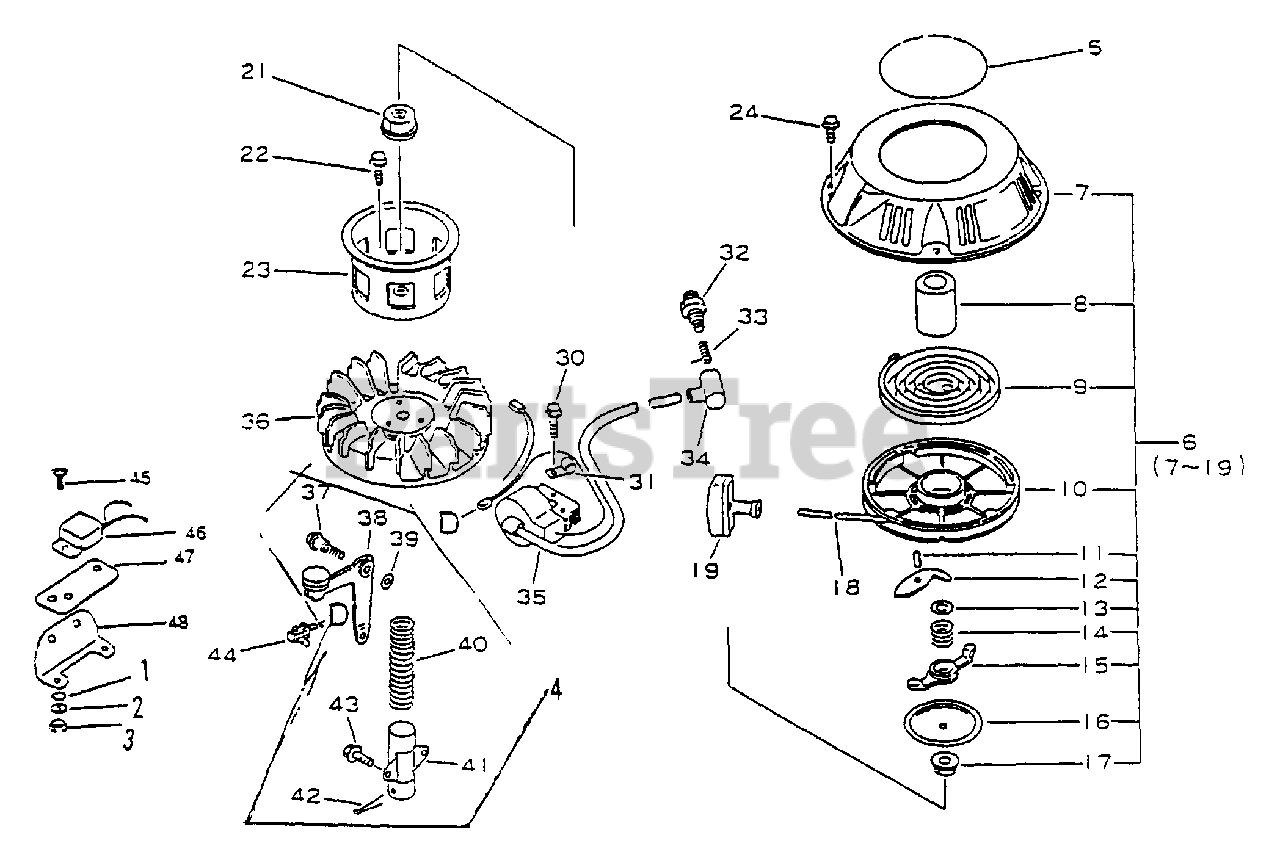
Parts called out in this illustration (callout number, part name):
1	WASHER 4 MM
2	WASHER, SPRING 4 MM
3	NUT M4
4	CHAIN BRAKE ASSY
5	LABEL - ECHO
6	STARTER ASSY
7	CASE, STARTER
8	BUSHING
9	SPRING, RECOIL
10	REEL, ROPE
11	PIN
12	PAWL, STARTER
13	WASHER
14	SPRING
15	GUIDE, PAWL
16	PLATE, FRICTION
17	NUT, FLANGE M6
18	ROPE, STARTER
19	GRIP, STARTER
20	CAP
21	NUT, 10 L-H
22	BOLT - 6×10
23	CATCHER, PAWL
24	SCREW - 6×10
30	BOLT - 6×25
31	CLIP
32	SPARK PLUG - BPM6A
33	TERMINAL, SPARK PLUG
34	CAP, SPARK PLUG
35	COIL, IGNITION
36	FLYWHEEL
37	SHAFT, BRAKE ARM
38	BRAKE ARM ASSY
39	WASHER 6
40	SPRING
41	HOLDER, SPRING
42	PIN, COTTER 3×30
43	BOLT - 6×10
44	SWITCH, IGNITION
45	SCREW 4×12
46	COIL, IGNITION
47	PLATE, EYE
48	BRACKET, IGNITION COIL
